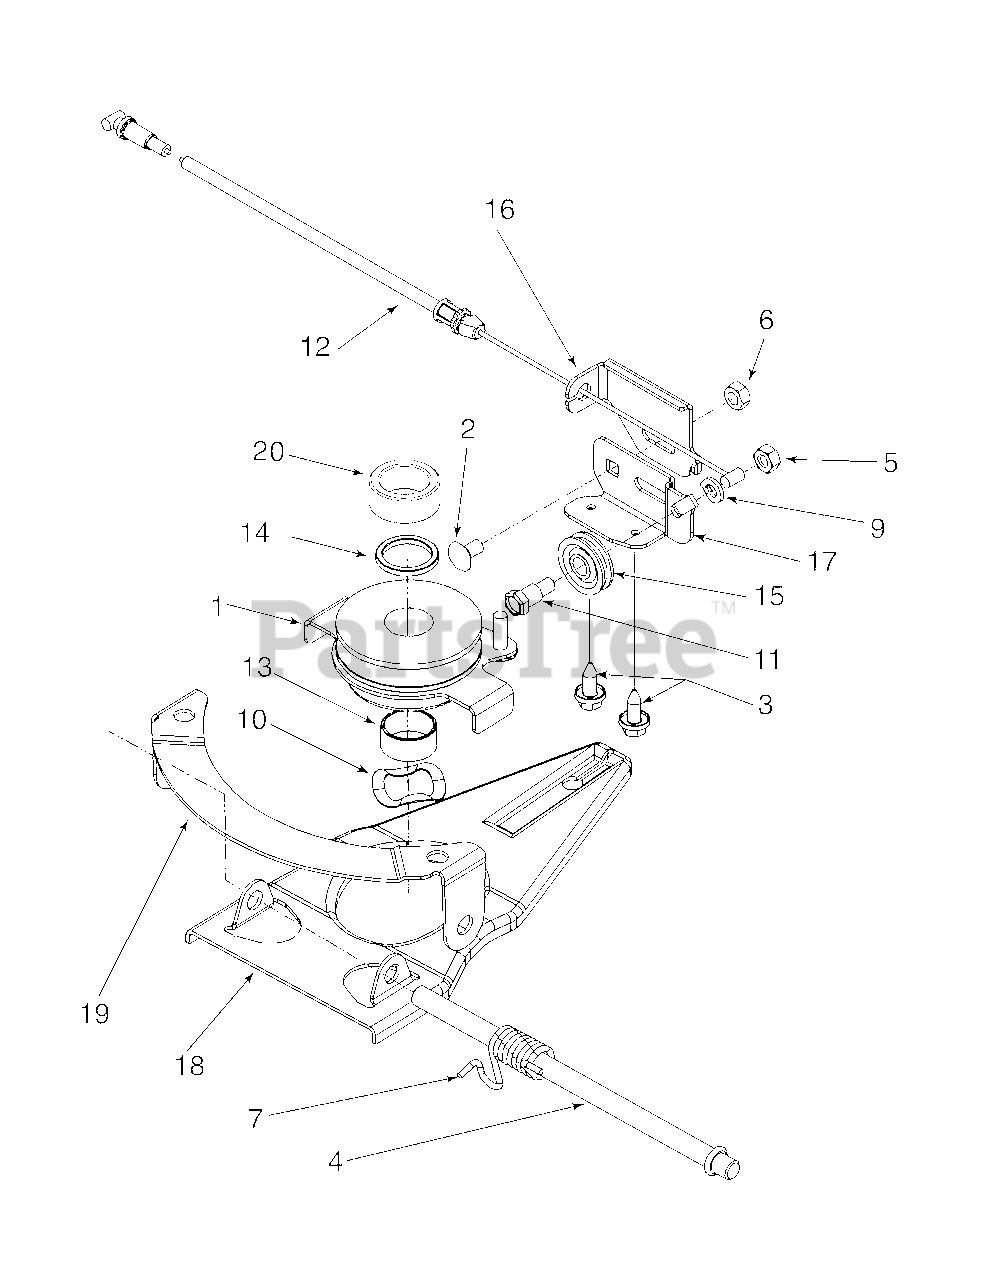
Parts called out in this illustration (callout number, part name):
1	Multi Speed Pulley Ass’y
2	Carriage Bolt 1/4-20 x .62\5" Lg. Gr. 2
3	Hex Wash HD. TT Tap Scr. 1/4-20 x .62
5	Hex Nut 1/4-28
6	Flanged Lock Nut 1/4-20 Gr. F Nylon
7	Torsion Spring LH
9	L-Wash 1/4 ID
10	Wave Washer .88 ID x 1.38 OD x .029
11	Hex Shld.Scr.1/4-28 x .375
12	Pulley Cable 53" Lg.
13	Sleeve Spacer .88 ID x 1.0 OD x .48
14	Sleeve Spacer .88 ID x 1.13 OD x .12
15	Cable Guide Roller
16	Cable Ad just ment Bracket
17	Cable Mount ing Bracket
18	Control Arm
